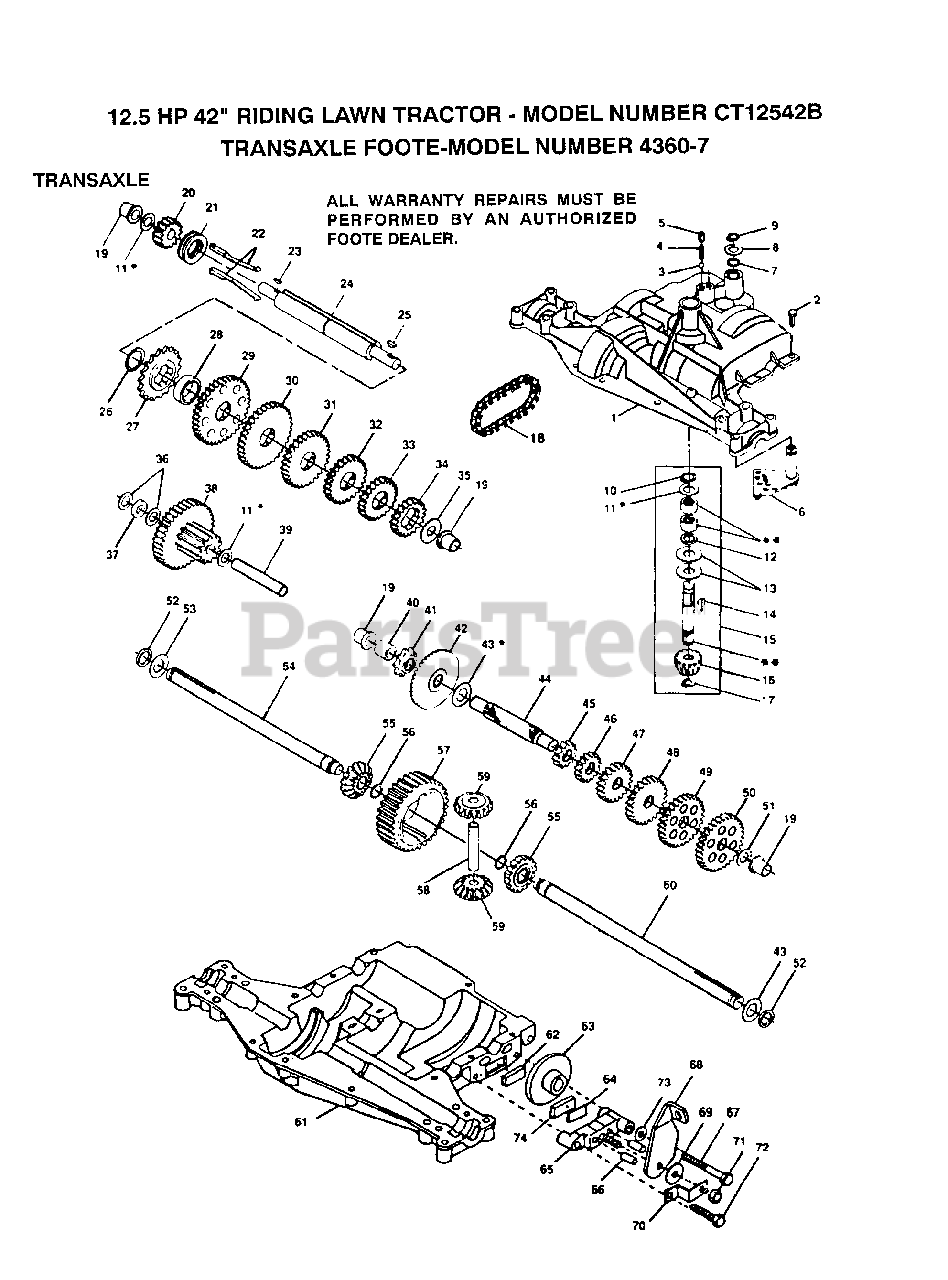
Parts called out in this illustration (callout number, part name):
2	BELT-V.92.4.MWR
3	BEARING
4	HSG ASM MANDREL
6	BEARING.BALL
8	WASHER BLADE
10	BLADE BOLT
12	DEFLECTOR.SHIELD
13	HINGE ROD
14	DEFLECTOR BRKT
15	NUT PUSH M
16	SPRING TORSION
17	WASHER
18	CAP-SLEEVE LT
20	BOLT
22	LINK.FRONT
23	NUT
24	TRUNION
25	NUT.LK.W/WSH.1/2.
26	LIFT LINK RH
27	SPRING PIN
29	LINK LIFT LH
33	IDLER ARM
35	WASHER
38	BOLT
39	HARDENED WASHER
40	FLAT IDLER PULLEY
41	SPACER RETAINER
42	WASHER GT
43	RETAINER SPACER
44	IDLER ARM STIFF
46	BOLT CARRIAGE
47	XMAS TREE FASTNER
48	SHOULDER BOLT
50	LOCKNUT
52	BRAKE PAD ARM ASM
53	HARD SMALL WASHER
54	SPRING EXTENSION
55	PIVOT ROD
57	CLUTCH ROD SECOND
60	NUT
61	TRUNION
62	RETAINER M
63	SCREW LT
64	BUSHING
65	RETURN SPRING
66	CLUTCH ARM SECOND
67	SHOULDER BOLT
68	RING
69	WASHER
70	SPRING KEEPER
72	CLUTCH ARM PRI AS
75	WASHER
77	PIN-GROOVE LT
78	NYLON BEARING
82	BUTTON PLUNGER YELLOW
83	GRIP
84	TRUNION LT
85	WASHER
86	KLIP RING
87	NUT T
88	WASHER
92	STIFFENER BRKT
94	SPRING T
97	BOLT
99	WASHER
